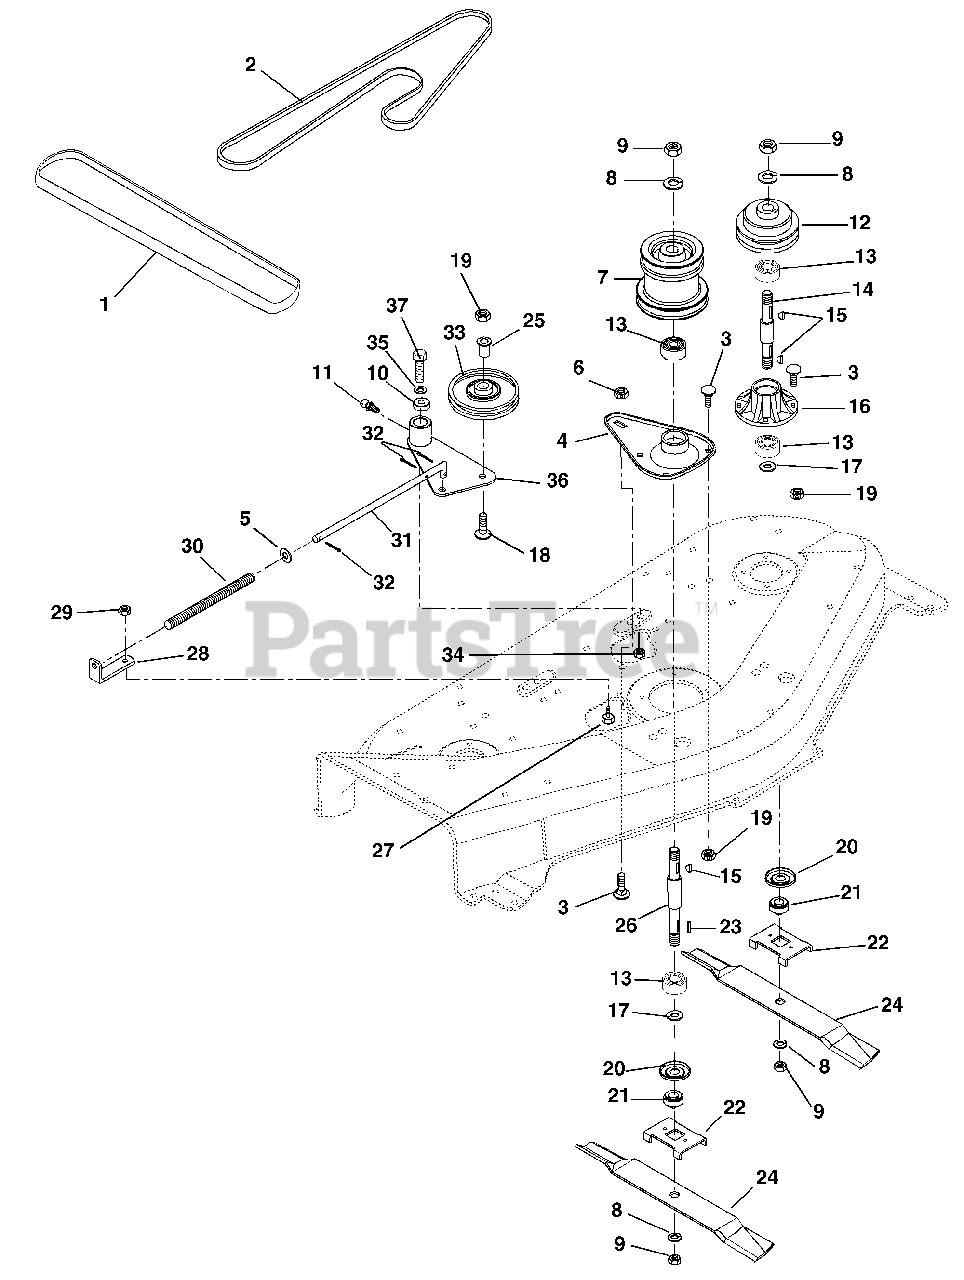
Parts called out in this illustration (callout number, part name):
1	V-BELT, HA-WRAPPED
2	V-BELT, HA-RAW EDGE
3	@BLT-RDHDSQNK .38-16X.75 G5YZ
4	HOUSING, SPINDLE
5	@WSHR-FL-STL.406X.812X.065 YWZ
6	@NUT-LK-TOP-FLG .38-16 YWZC
7	SHEAVE, 48" DECK
8	@WSHR-LK .75X.188 REG YWZC
9	NUT-JAM .75-10 YWZC
10	SPACER, PIVOT .500X.750X1.805
11	FTG-LUBE .25-28X.256 YWZC
13	BRG-BALL .750X1.781X.61
14	SPINDLE SHAFT
15	KEY-WDRF .188X.625X.25 SAE 61
16	SPINDLE HOUSING
17	WSHR-FL-STL .754X1.000X.032 YZ
18	BLT-BTHD .38-16X1.25 GR5
19	@NUT-LK-TOP-FLG .38-16 YWZC
20	BEARING SLINGER
21	RETAINER HUB
22	BLADE TRAY 48
23	KEY-SQ .188X.625X.188 SAE 61
25	SPACER -FLANGED .390X.500X.781
26	SHAFT-SPINDLE
27	@BLT-HEX .31-18X.50 GR5 YWZC
28	BRACKET
29	@NUT-LK-TOP-FLG .31-18 YWZC
30	SG-COMP .106X.63X 12.0 WLD 62
31	ROD-IDLER SPRING
32	@PIN-CTR .09X.75 EXTPRSQCT YWZ
33	IDLER, PLASTIC, 4.00 X .50 ID
34	@NUT-LK-TOP-FLG .50-13 YWZC
35	WSHR-FL-STL .505X.880X.072 YWZ
36	IDLER ARM
37	@BLT-HEX .50-13X2.75 GR5 YWZC
